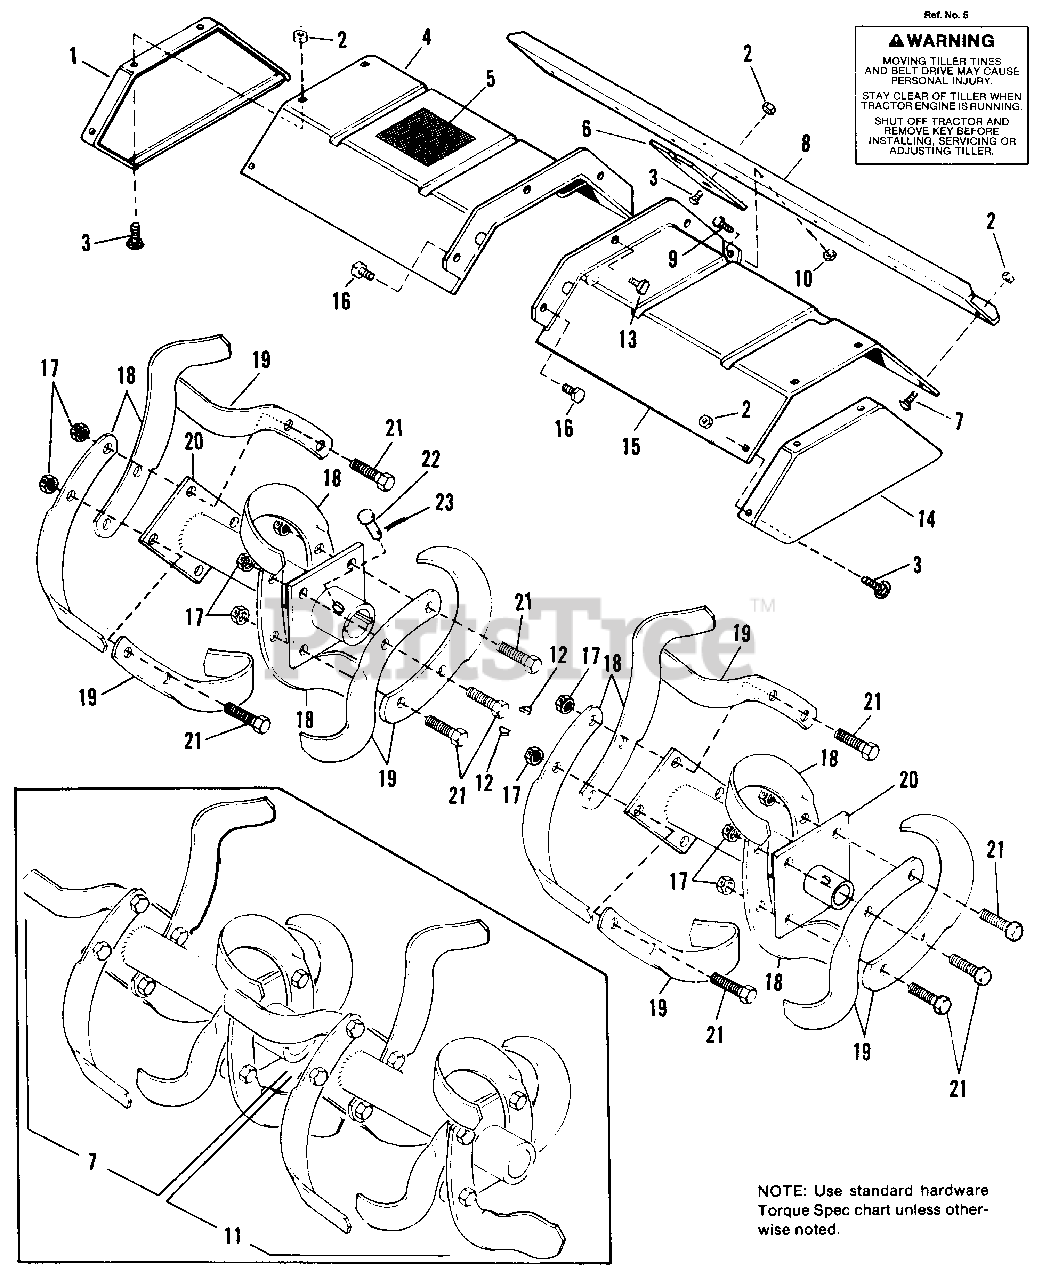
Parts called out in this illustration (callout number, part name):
1	PLATE, End Deflector, R.H.
2	LOCKNUT, Flange, 5/16-18
3	CARRIAGE BOLT, 5/16-18 x 5/8
4	DEFLECTOR ASSY., R.H.
5	DECAL, Safety
7	BLADE ASSY., L.H.
8	CHANNEL, Reinforcement
9	CAPSCREW, Hex Hd., 3/8-16 x 7/8
10	NUT, Hex, Flange Lock, 3/8-16
11	BLADE ASSY., R.H.
13	CAPSCREW, Hex Hd., 3/8-16 x 3/4
14	PLATE, End, Deflector, L.H.
15	DEFLECTOR ASSY, L.H.
16	SCREW, Hex, Whizlock, 3/8-16 x 1
17	LOCKNUT, Hex, 7/16-20
18	BLADE, Tine, R.H.
19	BLADE, Tine, L.H.
20	HUB & PLATE ASSY.
21	CAPSCREW, Hex Hd., 7/16-20 x 1-1/2
23	COTTER PIN, 1/8 x 3/4
